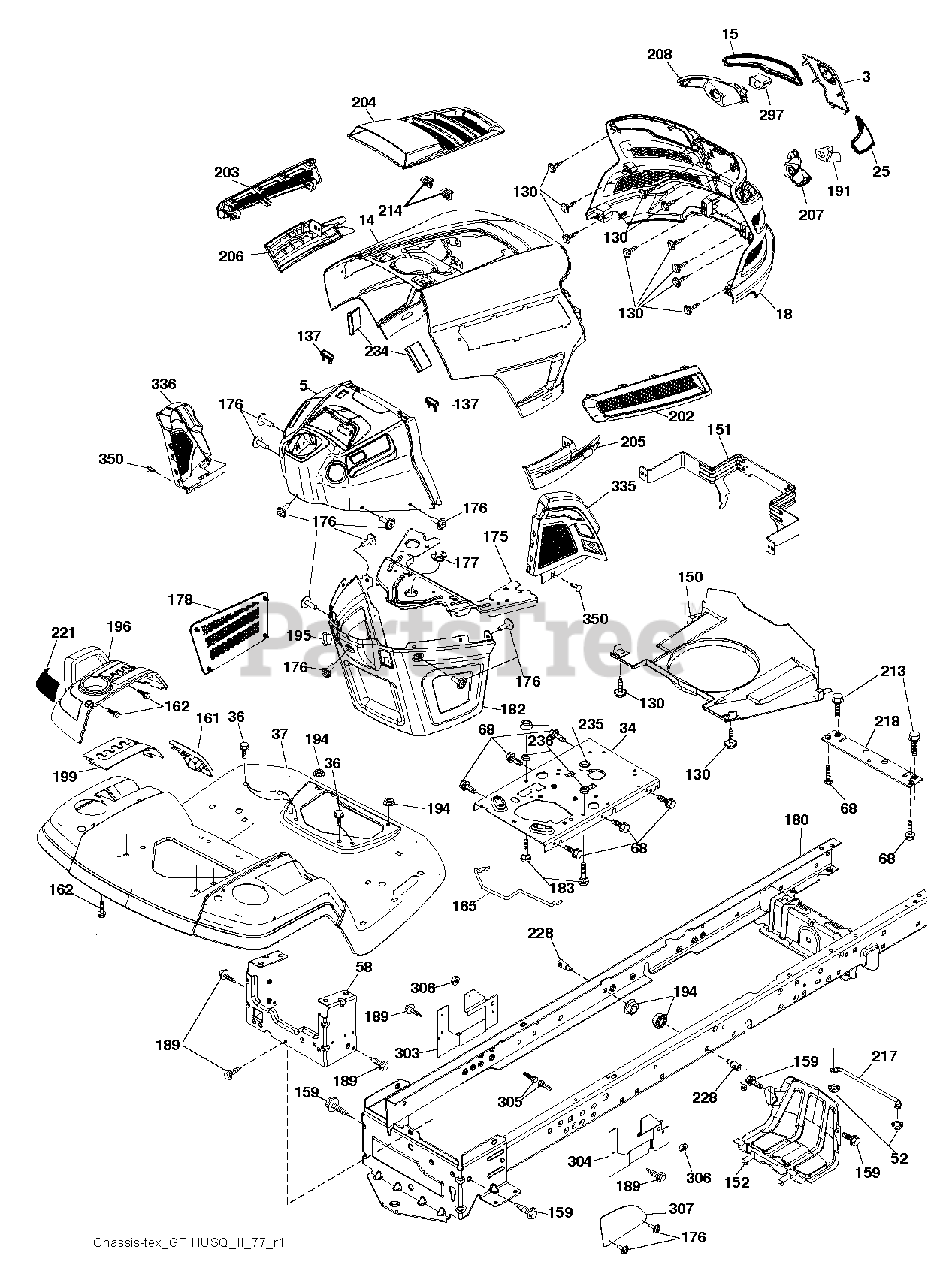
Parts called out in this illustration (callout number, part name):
3	APPLIQUE.SUBASM.GT.HUSQ.II
5	DASH.UPP.GT2.SM.PTO.MCHOKE
14	HOOD.ASM.HUSQVARNA.GT.TEX.ORAN
15	LENS.HEADLIGHT.LH.GTII.2011
18	GRILLE.SUBASM.GT.HUSQ.II
25	LENS.HEADLIGHT.RH.GTII.2011
34	PLATE PLATE ENGINE
36	SCREW 5/16"
37	FENDER.PNT.TX.GT.CH/FW/DL.HUSQ
52	LOCKNUT
58	DRAWBAR.UPPER.2PC,LRG.FENDER
68	SCREW LT
130	SCREW.#10 X 0.750.BOS
137	BUMPER DASH
150	AIR DUCT.GTV2(1.66"RING HEIGHT
151	BRACKET.PIVOT.HOOD.GT.HUSQ.II
152	SHIELD.BROWNING.PNT.GT.V2
159	SCREW, 3/8-16X3/4
161	CONSOLE.WINDOW.FUEL.HUSQ.GT
162	SCREW.HI-LO.CONSOLE
165	SUPPORT.TANK.REAR.W/TEX
175	PLATE.CROSSMEMBER.HUSQ
176	SCREW.#10-24X5/8.RN.QU
177	BUSHING, STEERING
178	CARGO.ASM.NET.TXGT.W/C
180	CHASS.WLDMNT.TLT.12GA/2PC.20"
182	DASH.LOWER.COMMON.12V.ADAPTOR
183	BOLT.5/16-18X1-1/4 FULL THD
189	SCREW
191	INSERT.REFLECTIVE.RH.HUSQ.GTII
194	NUT LOCK HEX FLANGE 5/16-18
195	PLUG.HOLE.DASH.LOWER.12V.BLK
196	SUBASM.CONSOLE.HUSQ.GT.DECKLFT
199	PLATE.DECK.LIFT.HUSQVARNA.GT
202	VENT.SIDE.RH.GT.HUSQ.II.
203	VENT.SIDE.LH.GT.HUSQ.II.498
204	VENT.TOP.HUSQ.GT2
205	SIDE.TRIM.RH.GT.HUSQ.II
206	SIDE.TRIM.LH.GT.HUSQ.II.GRAY
207	BEZEL LIGHT.RH.GT.II.MYLAR
208	BEZEL LIGHT.LH.GT.II.MYLAR
213	BOLT
214	CLIP.RETAINER.TINNER.
217	ROD.PIVOT.HOOD
218	X-PIECE.HOOD.STOP.NON/
221	REFLECTOR.LH.TEX GT HU
228	STUD.FASTNER.W/ANTI-ROTATE
234	BUMPER.HOOD.TEX.HUSQVARNA
235	SPACER FENDER
236	NUT.CENTERLOCK.5/16-
297	INSERT.REFLECTIVE.LH.HUSQ.GTII
303	SHIELD CHASSIS LEFT
304	SHIELD CHASSIS RIGHT
306	NUT LOCK FLG 3/8-16 UNC
307	SHIELD UPPER PEDAL
335	COVER.LOWER.DASH.RH.BLACK
336	COVER-LH.LOWER.DASH.GT2.BLACK
350	CLIP.X-MAS.TREE
